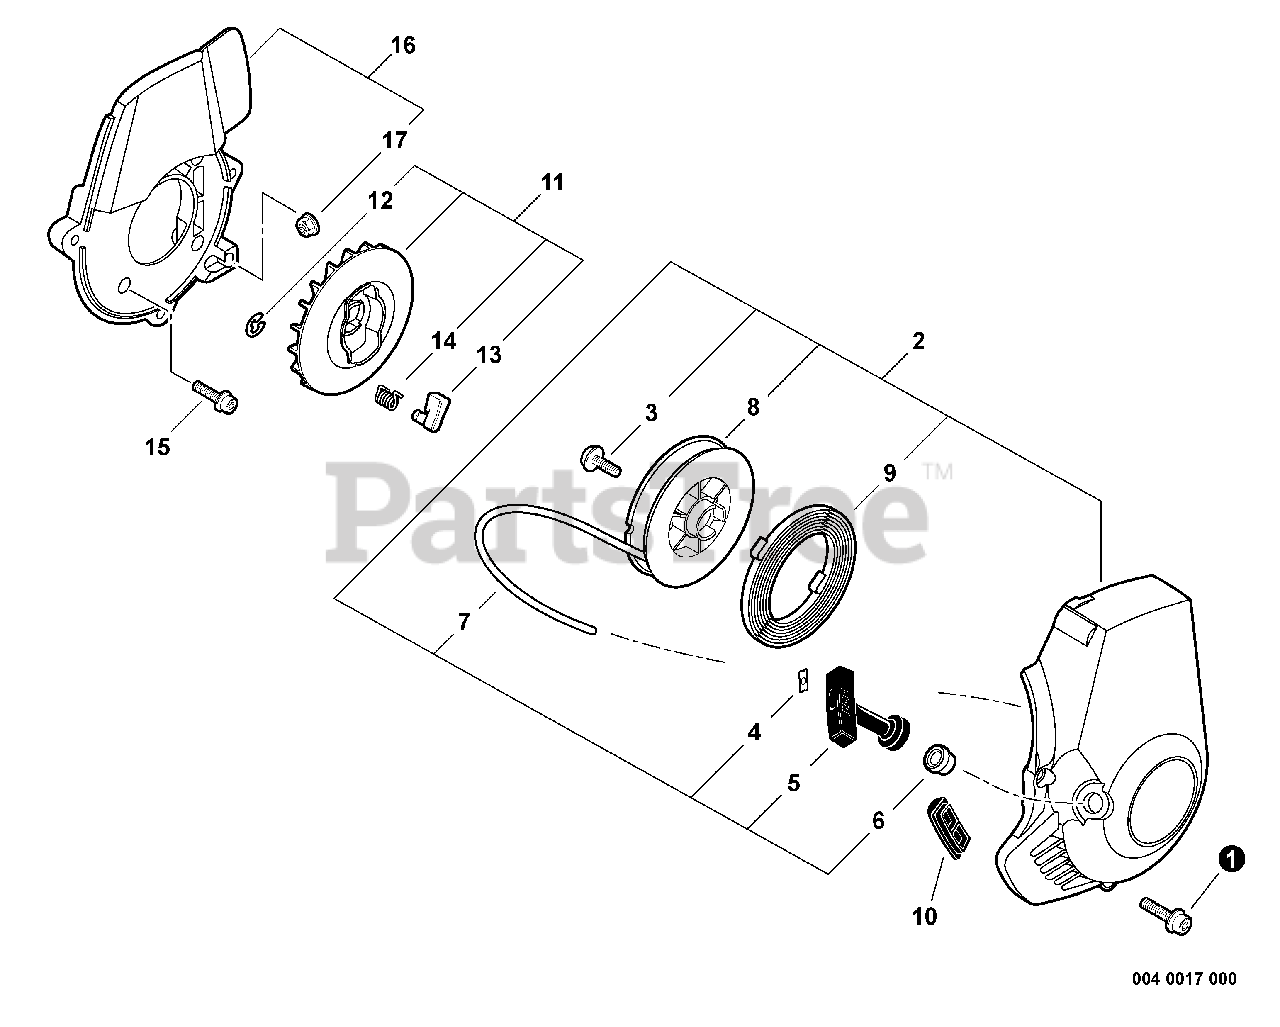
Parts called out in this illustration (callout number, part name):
1	BOLT 5×14
2	STARTER ASSY, RECOIL
3	SCREW
4	RETAINER, ROPE
5	GRIP, STARTER
6	GUIDE, ROPE
7	ROPE, STARTER 3×700
8	REEL, ROPE
9	SPRING, RECOIL
10	CUSHION
11	PAWL ASSY, STARTER
12	E-RING 4
13	PAWL, STARTER
14	SPRING, RETURN
15	BOLT 4×16
16	SPACER
17	NUT, FLANGE M5
